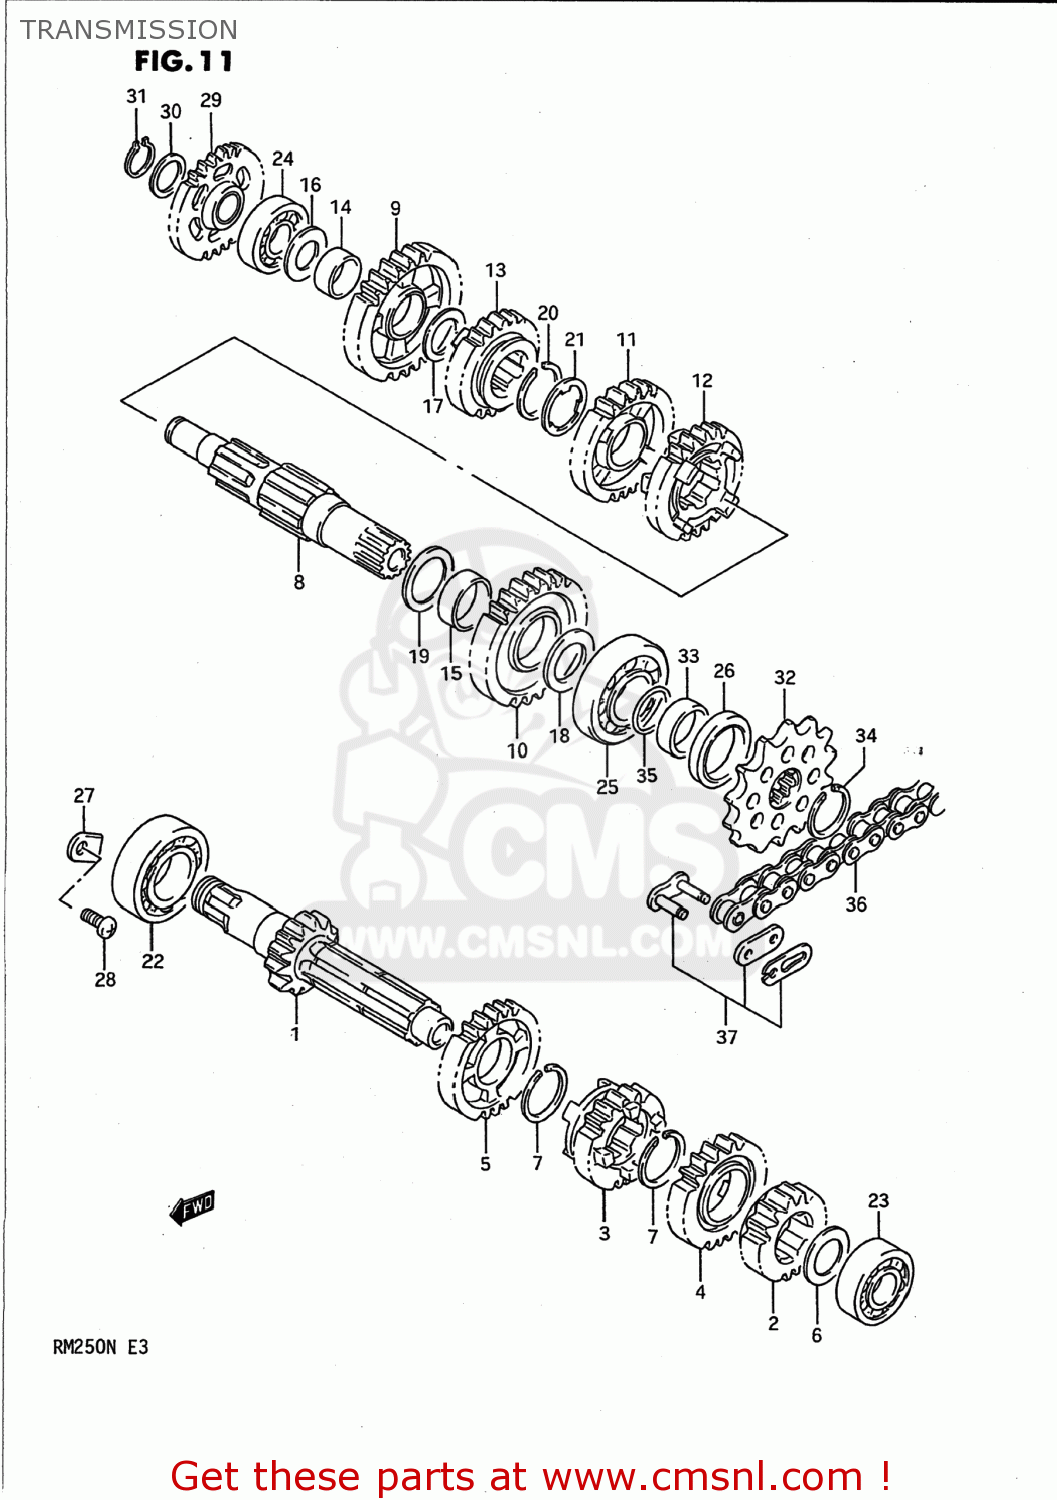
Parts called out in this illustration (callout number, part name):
1	SHAFT,COUNTER
2	GEAR,2ND DRIVE(NT:15)
3	GEAR,THIRD DRIVE
4	GEAR,FOURTH DRIVE
5	GEAR,FIFTH DRIVE
6	WASHER,THRUST
7	CIRCLIP
8	SHAFT,DRIVE
9	GEAR,FIRST DRIVEN
10	GEAR,2ND DRIVEN(NT:26)
11	GEAR,THIRD DRIVEN
12	GEAR,FOURTH DRIVEN
13	GEAR,FIFTH DRIVEN
14	BUSH(20X24X10)
15	BUSH(25X28X10)
16	WASHER,THRUST
17	WASHER
18	WASHER
19	WASHER
20	CIRCLIP
21	WASHER,LOCK
22	BEARING(25X52X15)
23	BEARING(17X40X12)
24	BEARING(17X40X12)
25	BEARING(22X56X15)
26	SEAL,OIL(28X38X6)
27	RETAINER,SHIFT CAM,R BEARING
28	SCREW 6X12
29	GEAR,KICK STARTER IDLE
30	SHIM
31	CIRCLIP
32	SPROCKET,ENGINE
33	SPACER,ENGINE SPROCKET
34	CIRCLIP
35	O RING(D:1.9,ID:21.8)
36	CHAIN ASSEMBLY,DRIVE
37	JOINT ASSEMBLY,CHAIN
